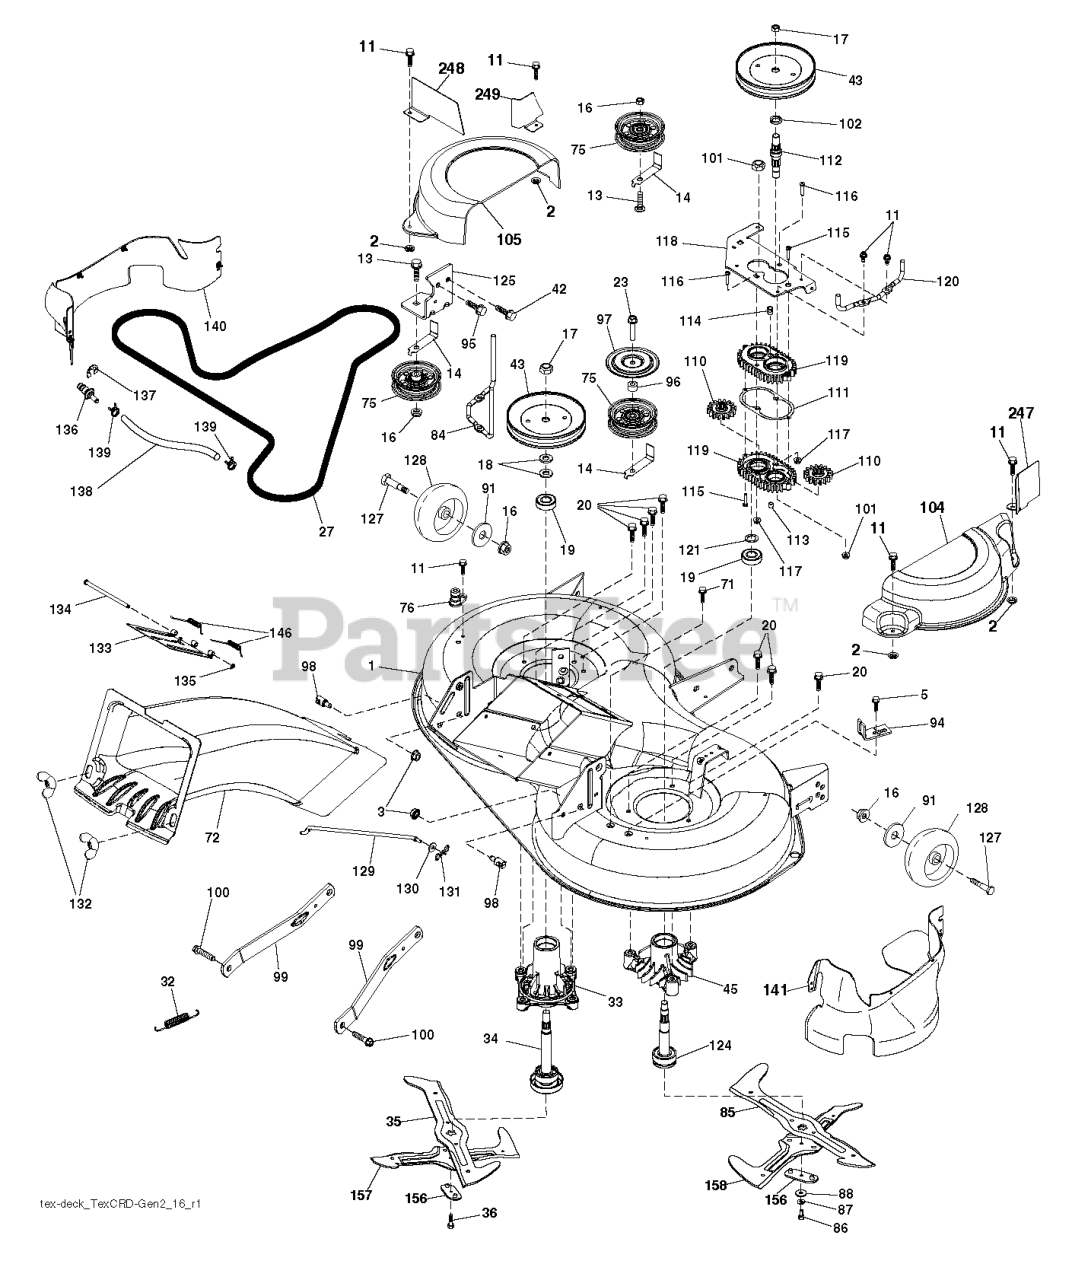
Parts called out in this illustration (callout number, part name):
3	NUT LOCK HEX FLANGE 5/16-18
5	BOLT.5/16HEX.WHS.HD
11	SCREW.1/4-20X5/8
13	BOLT.3/8-16X1.50
14	KEEPER, BELT IDLER
16	NUT LOCK FLG 3/8-16 UNC
17	NUT.FLANGE.LOCK.TOP
18	WASHER.SPACER.MANDREL
20	SCREW, WASHER HEAD
23	SCREW LT
27	BELT BELT. ELECTRIC MOWER DRIV
32	SPRING 107CM & 97CM ELECTRIC D
33	RP.HOUSING.MANDREL.4PT.
34	SHAFT.ASM.MDRL.N/GREASE.38
35	BLADE.3N1.LH.CRD
36	BOLT.WASHER.ASM.7/16-2
42	SCREW
43	PULLEY PULLEY MANDREL 5.438 PD
45	HOUSING.MANDREL.44/46" VENT
72	RP.97/107.TEX.CRD.UPPER CHUTE
75	FLAT IDLER PULLEY
76	1/2" BARB.DECK.WASHOUT.PORT
84	KEEPER KEEPER. LH MANDREL BELT
85	BLADE.3N1.RH.CRD
86	BOLT.3/8-24X1.25GR8. LHTHRD
87	LOCKWASHER
88	WASHER.BLADE
91	WASHER
94	BRKT.CLUTCH.CABLE
95	SCREW, 3/8-16X3/4
96	SPACER
97	PROTECTOR
98	STUD.FASTNER.W/ANTI-ROTATE
99	ARM.SUSPENSION.MOWER.R
100	BOLT.SHOULDER
101	NUT.CROWNLOCK.9/16 -18.UNC
102	SPACER BEARING
110	CRD.SPUR.GEAR
111	GASKET GASKET GEARCASE
112	SHAFT SHAFT. CRD GEARCASE ADAP
113	PLUG PLUG OIL
114	VALVE VALVE RELIEF
115	SCREW
116	BOLT.CARIGE.SS.1/4-20X1.75GR5
117	NUT T
118	ARM ARM. CLUTCHING 107 TEX CRD
119	GEARCASE GEARCASE SUBASM
120	KEEPER KEEPER. RH MANDREL BELT
121	WASHER WASHER
124	MANDREL SHAFT NON/GREASE
125	BRACKET BRACKET IDLER CHASSES
127	BOLT.SHOULDER.3/8-16X3-5/8.
128	RP WHEEL. GUAGE RALLY
129	ROD ROD. SWAY CRD GEN II
130	WASHER
131	PIN.COTTER.5/16.BOW TI
132	KNOB.HANDLE.3/8.TRI-POINT.BLAC
133	COVER DOOR.107 CM CRD EZ MULCH
134	PIN PIN.HINGE
135	E-RING.5/16"
136	PLUG WASHOUT PORT HOOKUP
138	107.WASHOUT.PORT.HOSE (2 2)
139	HOSE.3/8.CLAMP (2 2)
141	GUARD SUBASM. 107 TEX GEN 2 RH
146	SPRING SPRING: EZ MULCH DOOR
156	ADAPTER ADAPTER.CROSSBLADE.107
157	BLADE 107CM.CROSS.BLADE
158	BLADE.CROSS.RH.CRD.107
